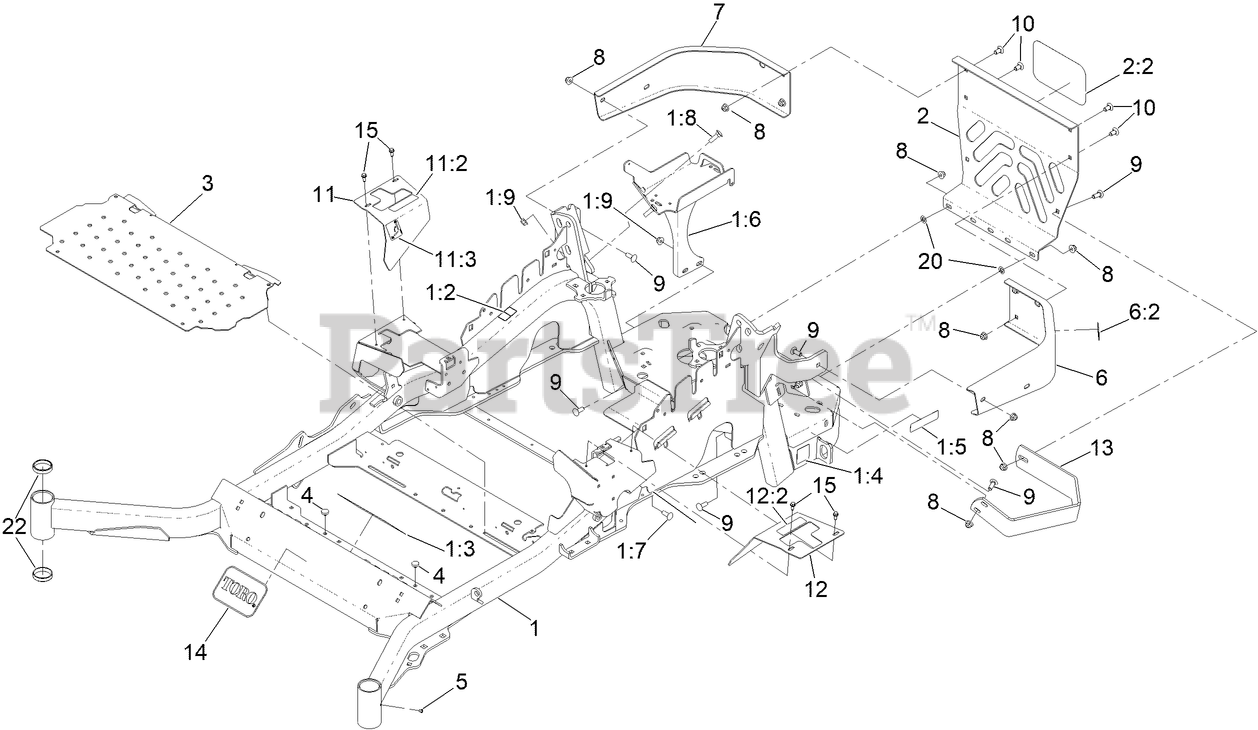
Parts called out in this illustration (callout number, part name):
1	MAINFRAME SERVICE ASM - 72
1:2	DECAL-WARNING
1:3	DECAL-DANGER
1:4	DECAL-HAZARD, PINCHED FINGER
1:5	DECAL-ARRESTOR, SPARK
1:6	BATTERY MOUNT ASM
1:7	SCREW-CARR
1:8	BOLT-CARR
1:9	NUT-HF, NI
2	REAR GUARD ASM
2:2	DECAL
3	FLOORPAN
4	BUMPER
6	LH BUMPER ASM
6:2	DECAL-WARNING
7	BUMPER-RH
8	NUT-HF, NI
9	SCREW-CARR
10	SCREW-CARR
11	RH MOTION CONTROL COVER ASM
11:2	DECAL-CONTROL, MOTION
11:3	DECAL-PARK BRAKE, CE
12	LH MOTION CONTROL COVER ASM
12:2	DECAL-CONTROL, MOTION
13	GUARD-MUFFLER
14	DECAL
15	SCREW-HWH
20	NUT-PUSH
22	CUP-BEARING
